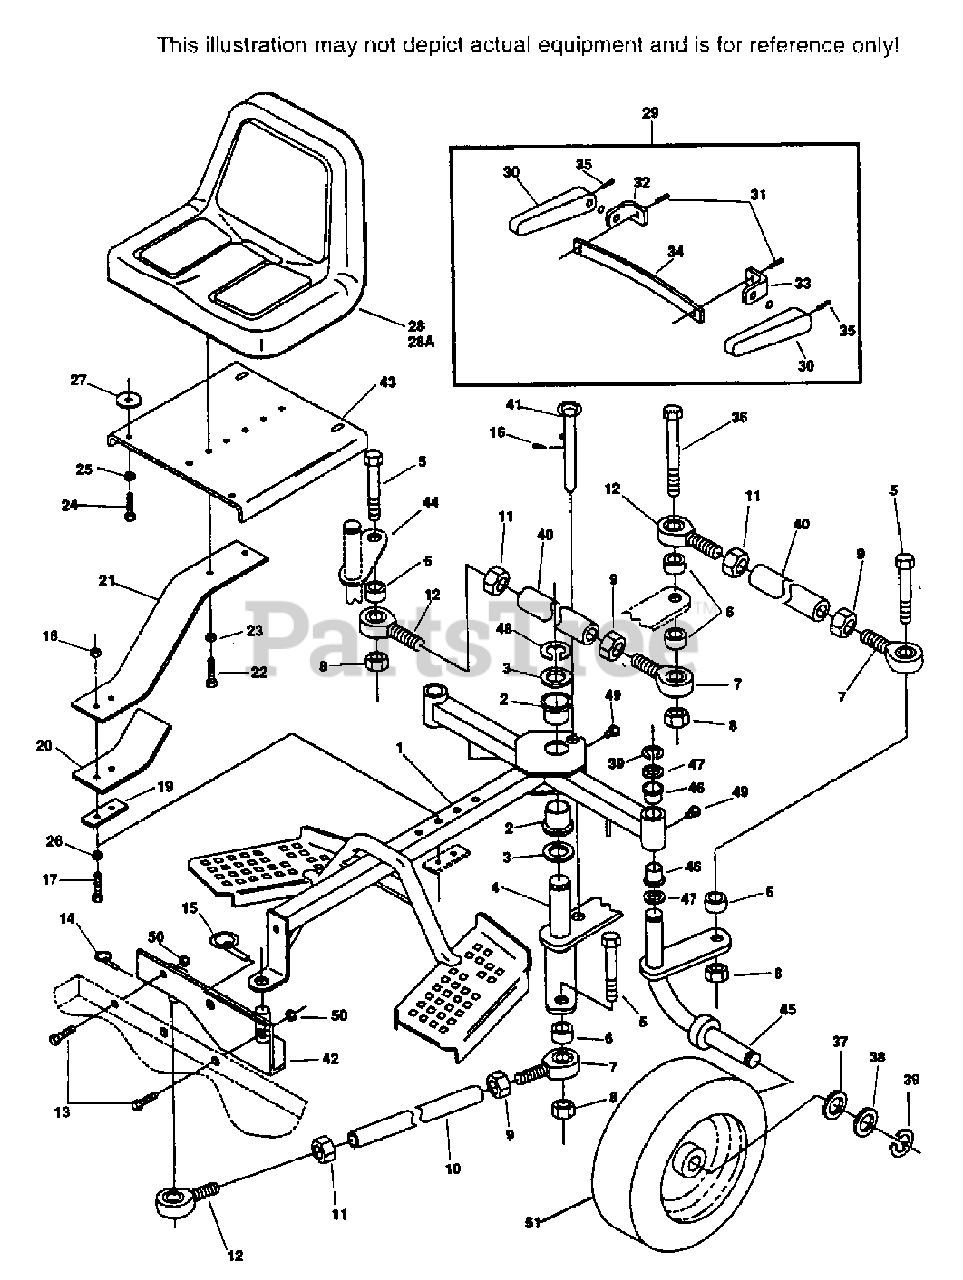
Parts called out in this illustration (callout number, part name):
1	SULKY FRAME
2	BRONZE BEARING
3	FLAT WASHER
4	STEERING BELLCRANK
6	BALL JOINT SPACER
7	BALL JOINT(R.H. THREAD), 1/2-20
10	TIE ROD, LONG
11	HEX NUT(L.H. THREAD), 1/2-20
12	BALL JOINT(L.H. THREAD), 1/2-20
14	QUICK PIN - SMALL
15	QUICK PIN - LARGE
16	HAIR PIN
19	LOWER SUPPORT PLATE
20	REINFORCEMENT SEAT SPRING
21	SEAT SUPPORT SPRING
28	SEAT ASSEMBLY
28A	SEAT
29	ARM REST KIT
30	ARM REST
32	MOUNTING BRACKET R.H.
33	MOUNTING BRACKET L.H.
34	BACK STRAP
35	SET SCREW, 3/8-16 X 3/4" FLAT POINT
37	FLAT WASHER 1"
38	FLAT WASHER 1"
39	"E" CLIP 1"
40	TIE ROD
41	RING PIN
42	CENTER-STEERING MOUNTING BRACKET
43	SEAT PLATE
44	WHEEL SPINDLE R.H.
45	WHEEL SPINDLE L.H.
46	BRONZE BEARING
47	FLAT WASHER
48	"E" CLIP
49	GREASE FITTING
51	WHEEL ASSEMBLY
